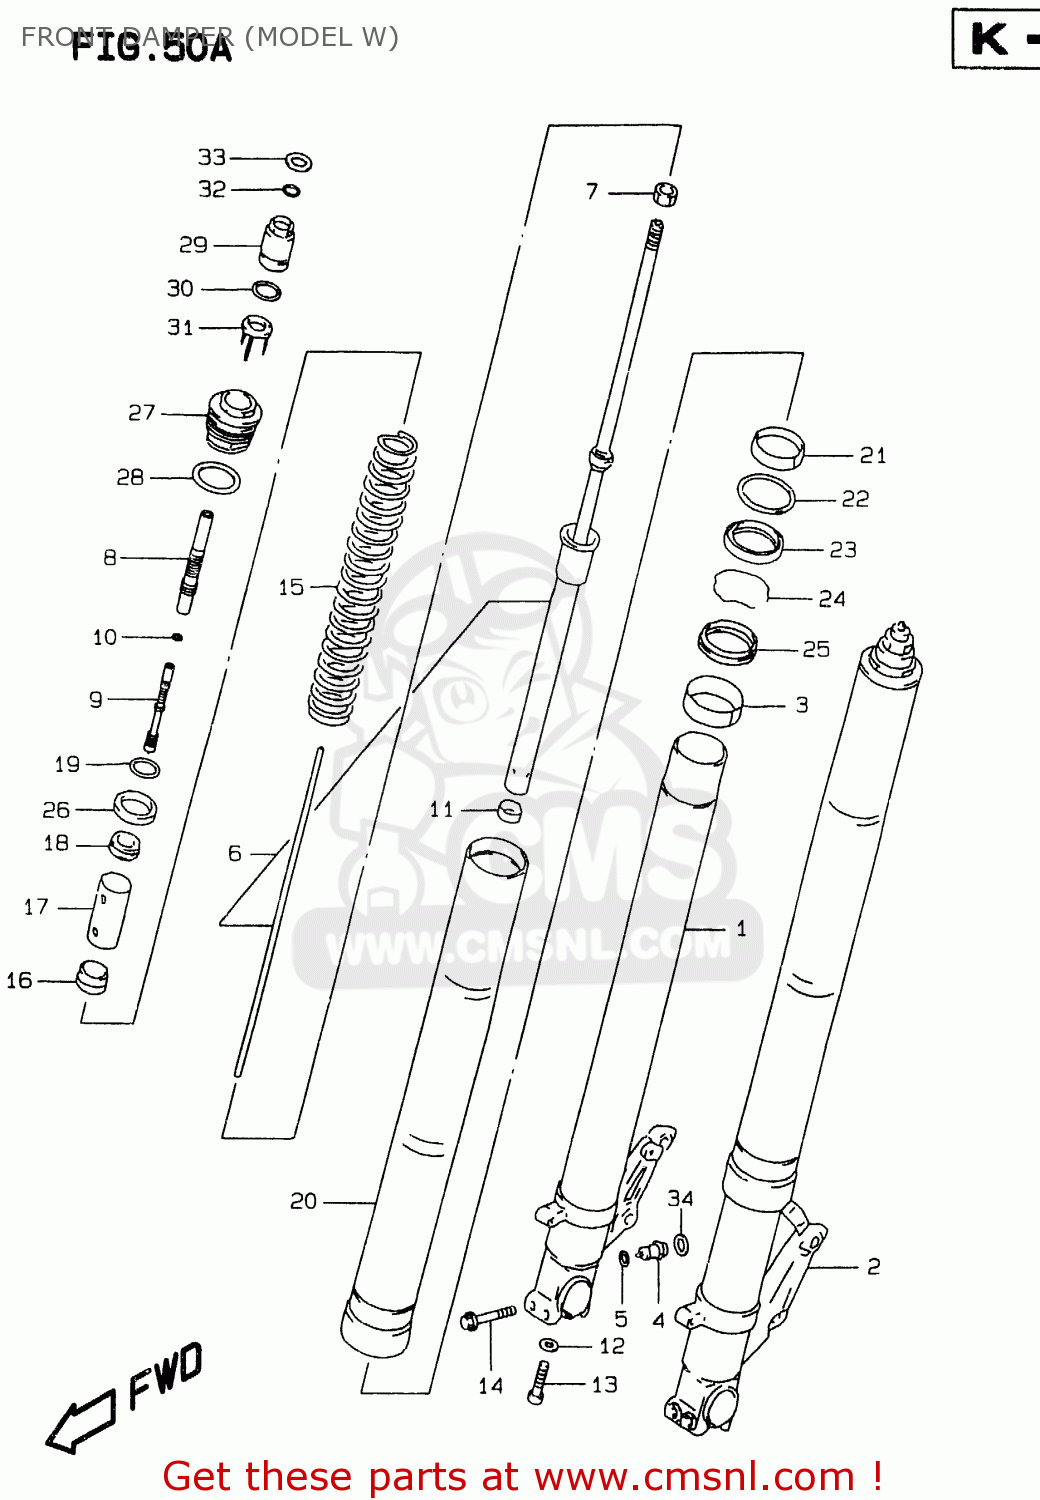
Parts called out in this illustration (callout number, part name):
1	TUBE,INNER,R
2	TUBE,INNER,L
3	BUSH,SLIDE
4	PIECE,ADJUST
5	O RING(D:2.5,ID:13.8)
6	ROD,FR DAMPER
7	NUT
8	CASE,ADJUSTER
9	PIECE,ADJUST
10	O RING(D:1.9,ID:3.8)
11	PLATE,CENTERING
12	WASHER(10X15X1.5)
13	BOLT
14	BOLT
15	SPRING,FR
16	JOINT,SPRING
17	COLLAR,SPRING
18	GUIDE,SPRING UPR
19	GUIDE,SPRING
20	TUBE,OUTER
21	BUSH,GUIDE
22	SPACER,SEAL
23	SEAL,OIL
24	CIRCLIP,FORK OIL SEAL
25	SEAL,DUST
26	RUBBER,SEAT
27	BOLT,FORK
28	O RING,FORK BOLT
29	ADJUSTER,SPRING
30	O RING
31	PLATE,SPRING ADJUSTER
32	RING,STOPPER
33	LABEL,ADJUST PIECE UPR
34	LABEL,ADJUST PIECE LWR
